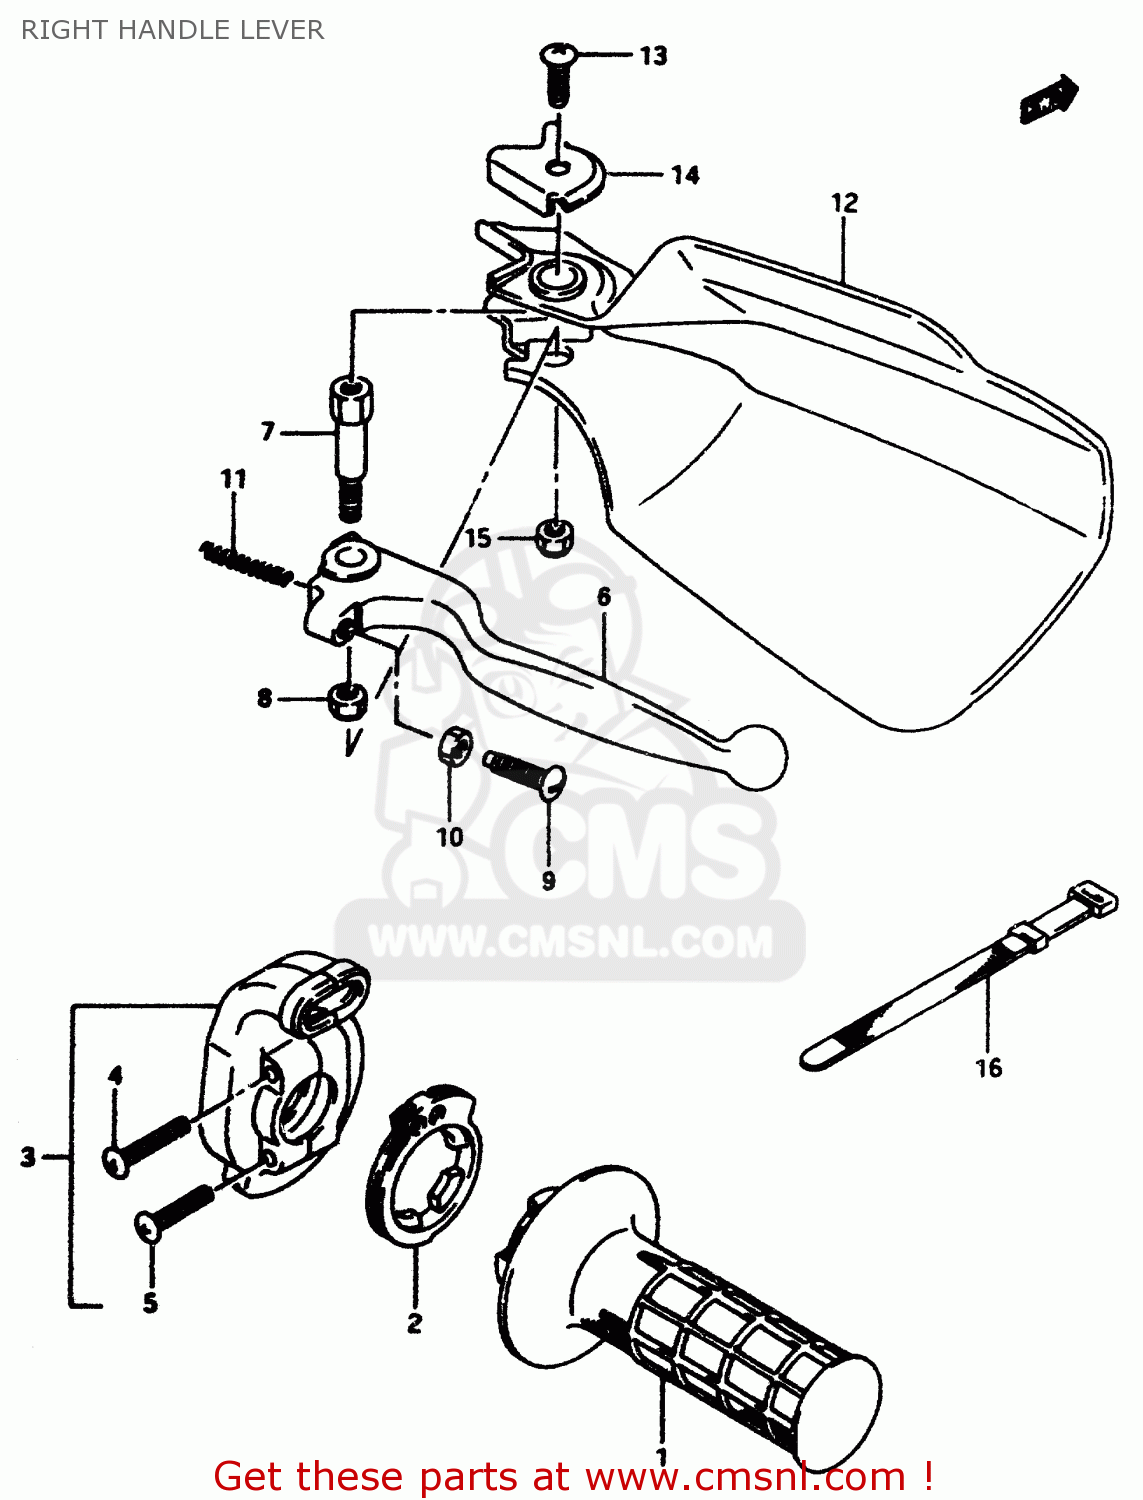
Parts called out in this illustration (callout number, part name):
1	GRIP,THROTTLE
2	ROTOR,THROTTLE GRIP
3	CASE ASSY,THROTTLE
4	SCREW(5X25)
5	SCREW
6	LEVER,BRAKE
7	BOLT,BRAKE LEVER PIVOT
8	NUT 6MM
9	BOLT,ADJUST
10	NUT
11	SPRING,RETURN
12	COVER,KNUCKLE,RH (YELLOW)
13	SCREW
14	PLATE,KNUCKLE COVER,R UPR
15	NUT 6MM
16	CLAMP(L:120)
